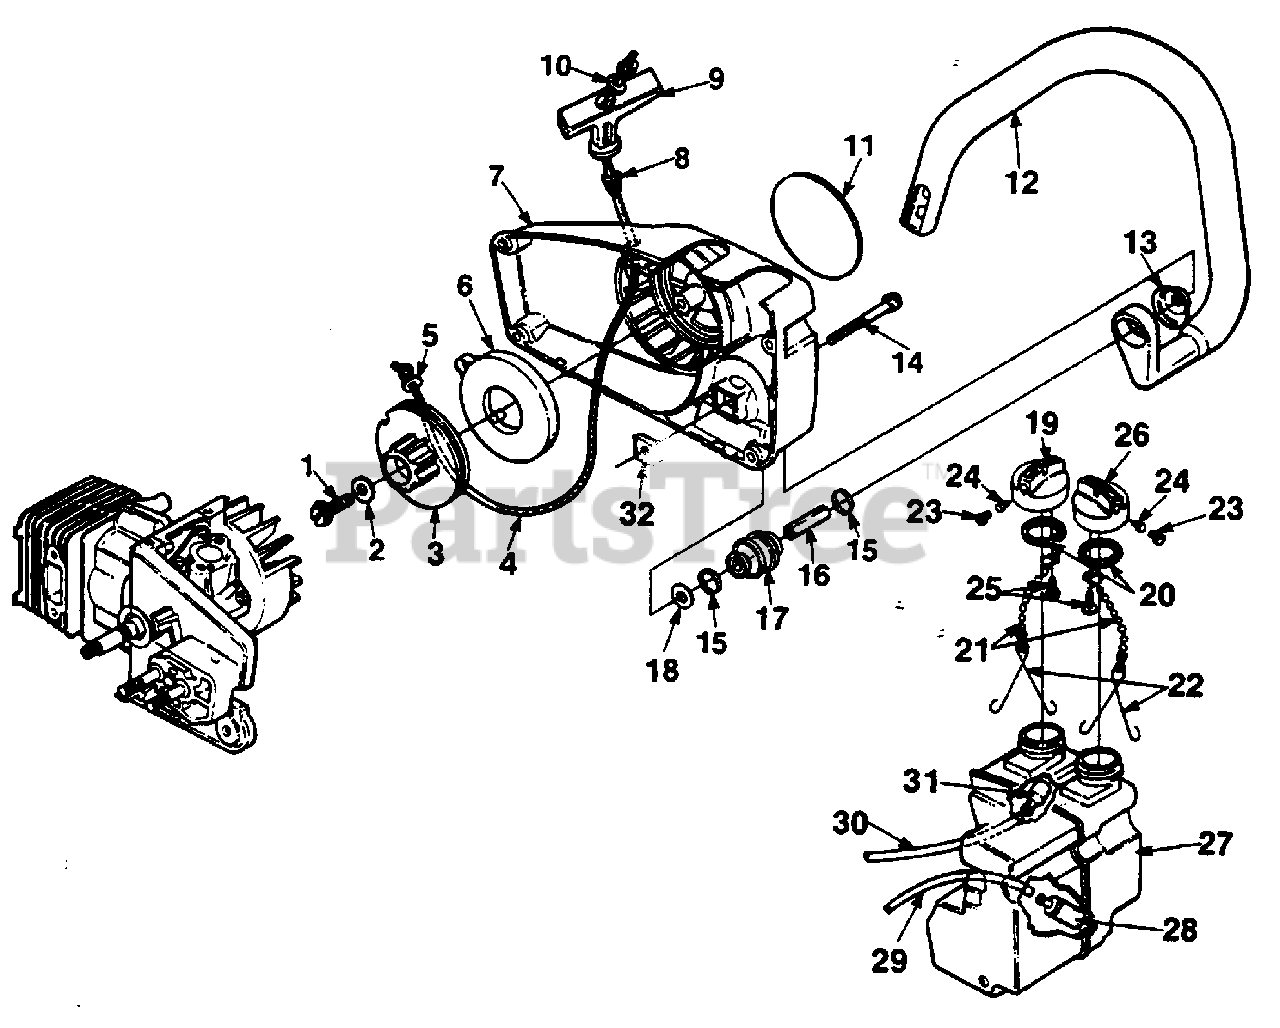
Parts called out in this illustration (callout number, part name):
1	SCREW- #10 x 3/4
2	WASHER- Retainer
3	PULLEY- Starter
4	ROPE- Starter #4 34"
5	WASHER- Nylon
6	SPRING & CONTAINER
7	HOUSING- Starter
8	BUSHING- Starter hsg.
9	GRIP- Starter rope
10	WASHER- Flat #8
11	DECAL-"245"
12	HANDLE BAR
13	WASHER- Vibration isolator
14	SCREW- Soc. hd. cap (10-24 x 1 5/8)
15	RING- Vibration isolator
17	ISOLATOR
18	WASHER- Flat
19	CAP- Oil
20	GASKET- Filler cap
21	BEAD- Chain
22	RETAINER
23	FILTER- Fuel cap
25	SCREW- Pan hd.
26	CAP- Fuel
27	TANK- Fuel & oil
28	FILTER- Fuel
29	TUBING- Fuel 6 1/2"
30	TUBING- Oil outlet 6 3/4"
31	FILTER- Oil
32	NUT- Square 10-24
